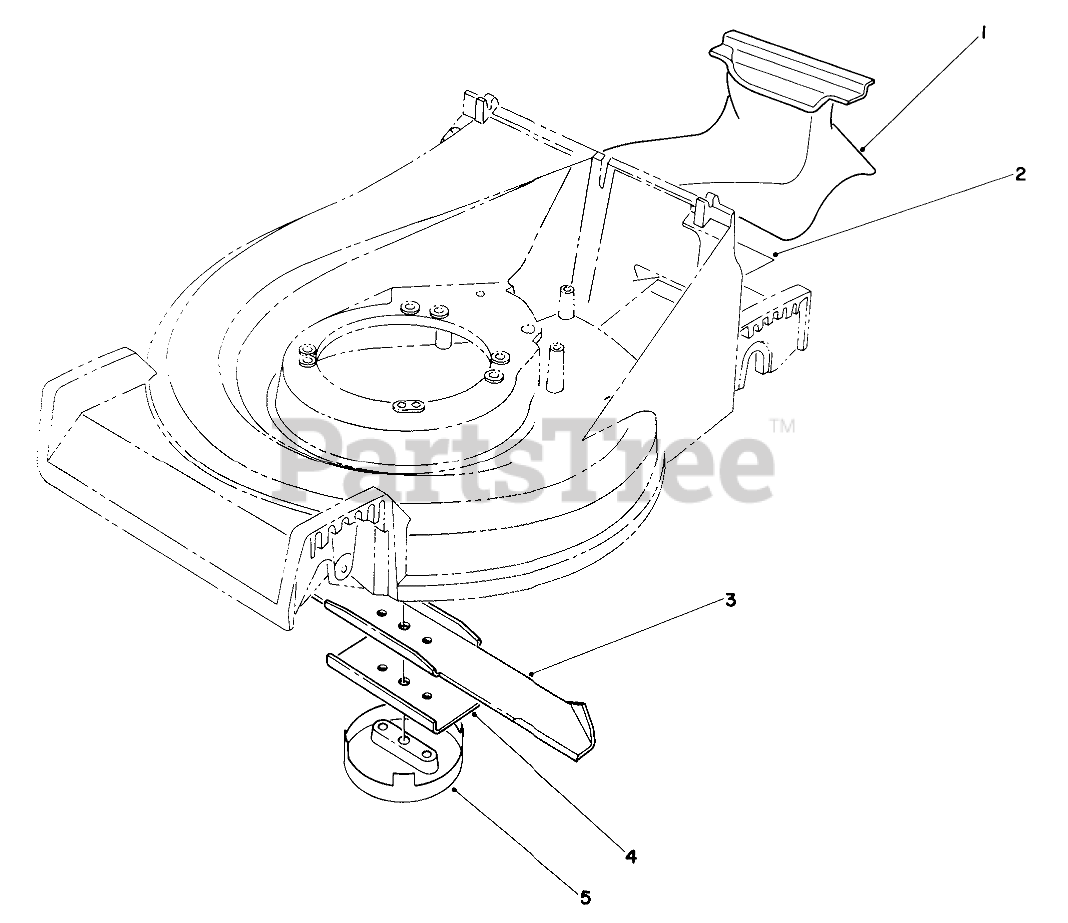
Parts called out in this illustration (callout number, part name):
1	RECYCLER PLUG
2	DECAL - MULCHER KIT
3	BLADE-21in
4	Stiffener
5	CUP-SCALP, ANTI
